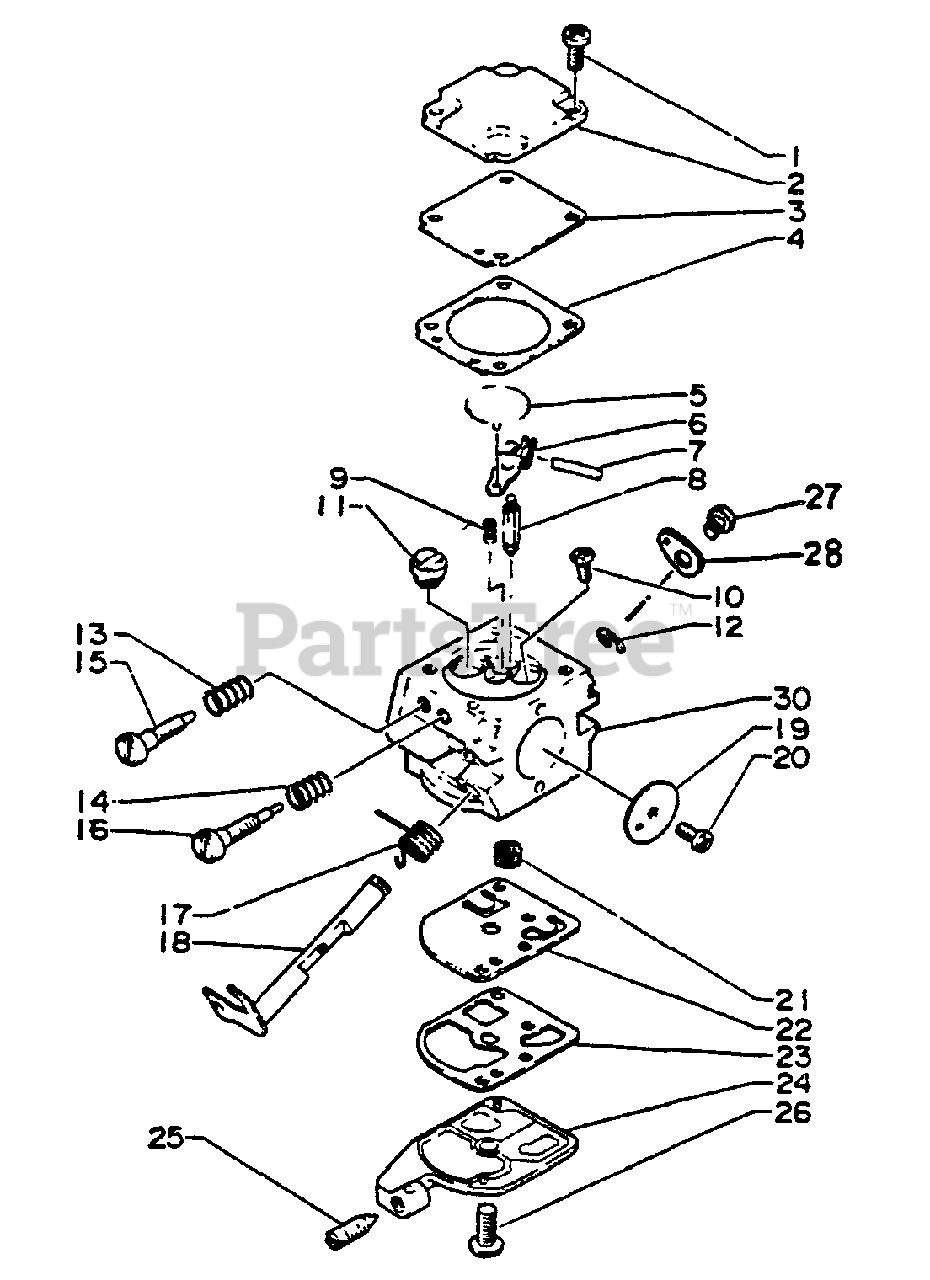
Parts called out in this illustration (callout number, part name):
1	SCREW
2	COVER, METERING
3	DIAPHRAGM
4	GASKET, METERING
5	PLUG, WELCH
6	LEVER, METERING
7	PIN, METERING LEVER
8	NEEDLE, INLET
9	SPRING, METERING LEVER
10	SCREW, METERING LEVER PIN
11	ORIFICE, MAIN FUEL
12	RING, RETAINING
15	NEEDLE - HIGH SPEED
16	NEEDLE - LOW SPEED
17	SPRING, RETURN
18	SHAFT, THROTTLE
19	VALVE, THROTTLE
20	SCREW
21	STRAINER
22	DIAPHRAGM, PURGE
23	GASKET, PURGE
24	BASE, PURGE
25	SCREW, IDLE ADJUST
26	SCREW, PUMP COVER
28	LEVER, THROTTLE
